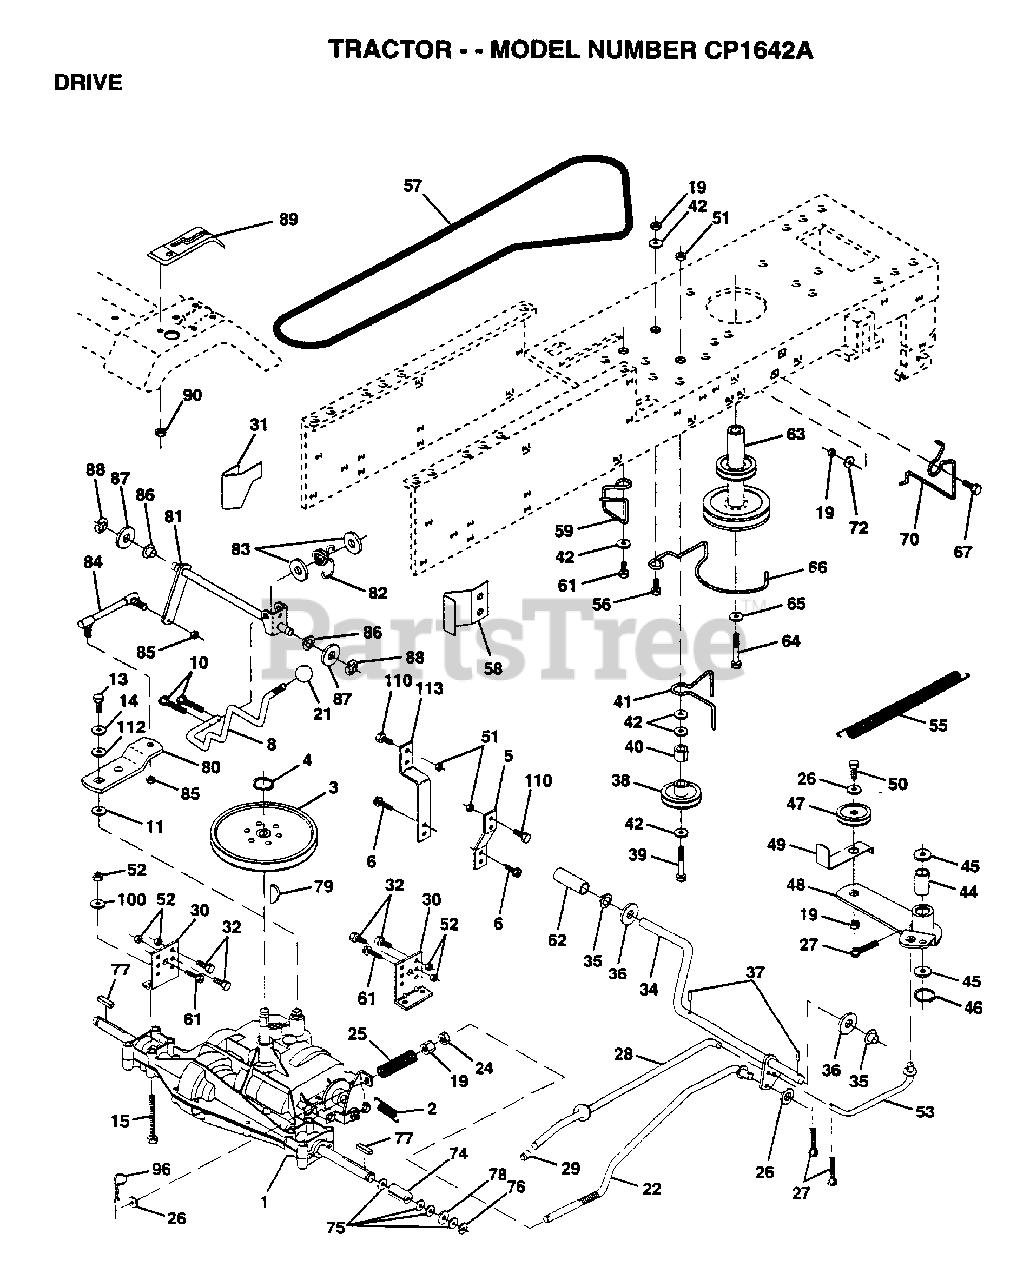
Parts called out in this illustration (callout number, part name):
2	SPRING.BRAKE.RETU
3	PULLEY TRANS
5	STRAP TORQUE
6	SCREW
8	ROD SHIFT FEND LT
10	PIN COTTER 1/8
11	WASH-SHFT PLT LT
13	BOLT.1/4-28.W/PAT
14	LOCKWASHER
15	BOLT HEX
18	BOLT
19	NUT
21	KNOB T (1/2-HOLE)
22	BRAKE ROD
24	NUT
25	SPRING ROD LT
26	WASHER
27	COTTER PIN
28	ROD.BRAKE.PARK.LT
29	PLUNGER CAP T
30	TRANSAXLE MTG BKT
31	"KEEPER,BELT LH T"
32	BOLT
34	SHAFT.PEDAL.FOOT
35	NYLON BEARING
36	WASHER LT
38	PULLEY.IDLER.FLAT
39	BOLT
40	SPACER T
41	BELT KEEPER LT
42	WASHER
44	"LY, BEARING"
45	WASHER LT
46	KLIP RING
48	ARM IDLER
49	RETAIN BELT
53	"LINK, CLUTCH T"
55	"SPRING, RETURN LT"
58	"KEEPER,BELT RH T"
59	KEEPER BELT CNTSP
61	SCREW
62	PEDAL COVER T
63	PULLEY.ENGINE
64	BOLT
65	LOCKWASHER
66	KEEPER.BELT.ENG.L
67	BOLT
70	KEEPER BELT ENG
72	WASHER
74	SPACER AXLE
75	WASHER
76	E-RING LT
77	SQUARE KEY
78	WASHER
80	"ARM.SHIFT.20""TIRE"
82	"SPRING,TORSION"
83	WASHER
84	TIE ROD
85	NUT 1/4-28
86	BUSHING
87	WASHER D
88	KLIP RING
90	NUT
96	RETAINER M
100	WASHER M
112	WASHER LT
113	"STRAP,TORQUE"
